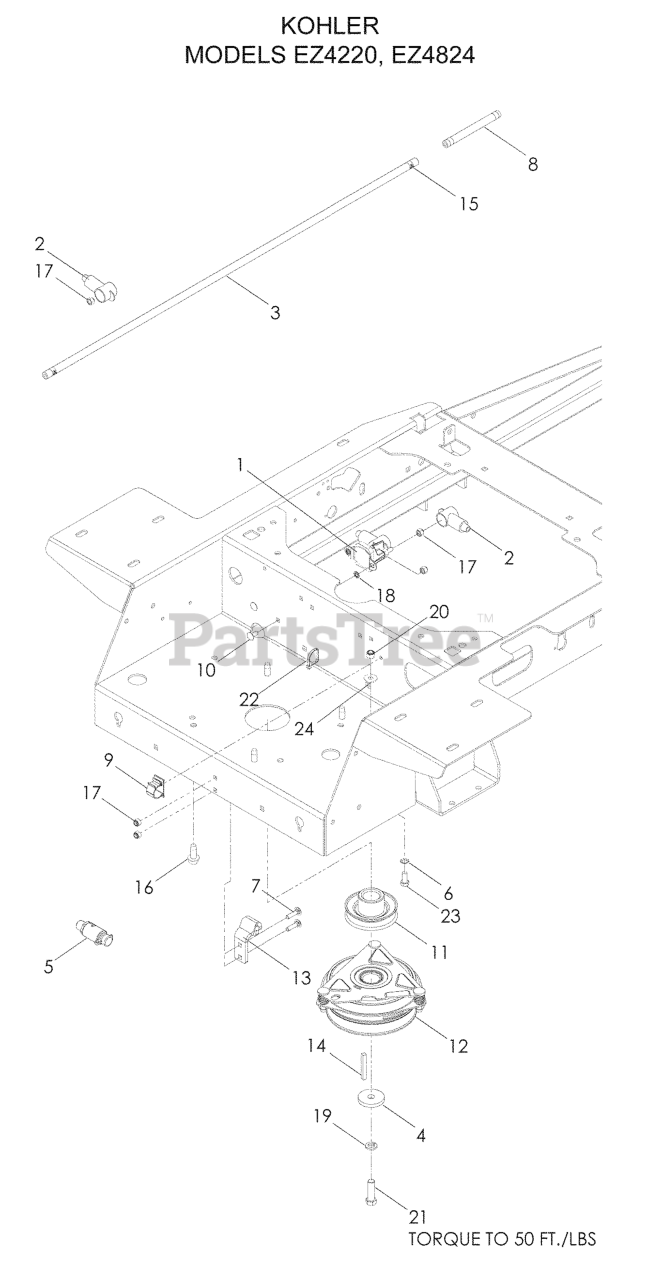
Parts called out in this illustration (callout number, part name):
4	SPINDLE WASHER
5	OIL DRAIN FITTING
6	WASHER 5/16 EXT STAR
7	RHSNB, 1/4-20 X 1, GR5
8	FUEL LINE 5"
9	PUSH-MOUNT WIRE CLIP
10	RHSSNB, 1/4-20X5/8
11	PULLEY, DRIVE
12	CLUTCH, 150 FT/LBS
13	TIE DOWN, CLUTCH
14	KEY 1/4 SQ X 2
15	HOSE CLAMP
16	BOLT 3/8-16 X 1.0
17	NUT.1/4-20.HEX.NYLOC.ZD
18	WASHER 1/4 INT TOOTH
19	WASHER 7/16 LOCK
20	NUT 5/16 NYLOC
21	HCS 7/16F X 1 1/2
22	TIE, PLASTIC
23	HCS 5/16C X 3/4
24	WASHER 5/16 FLAT
